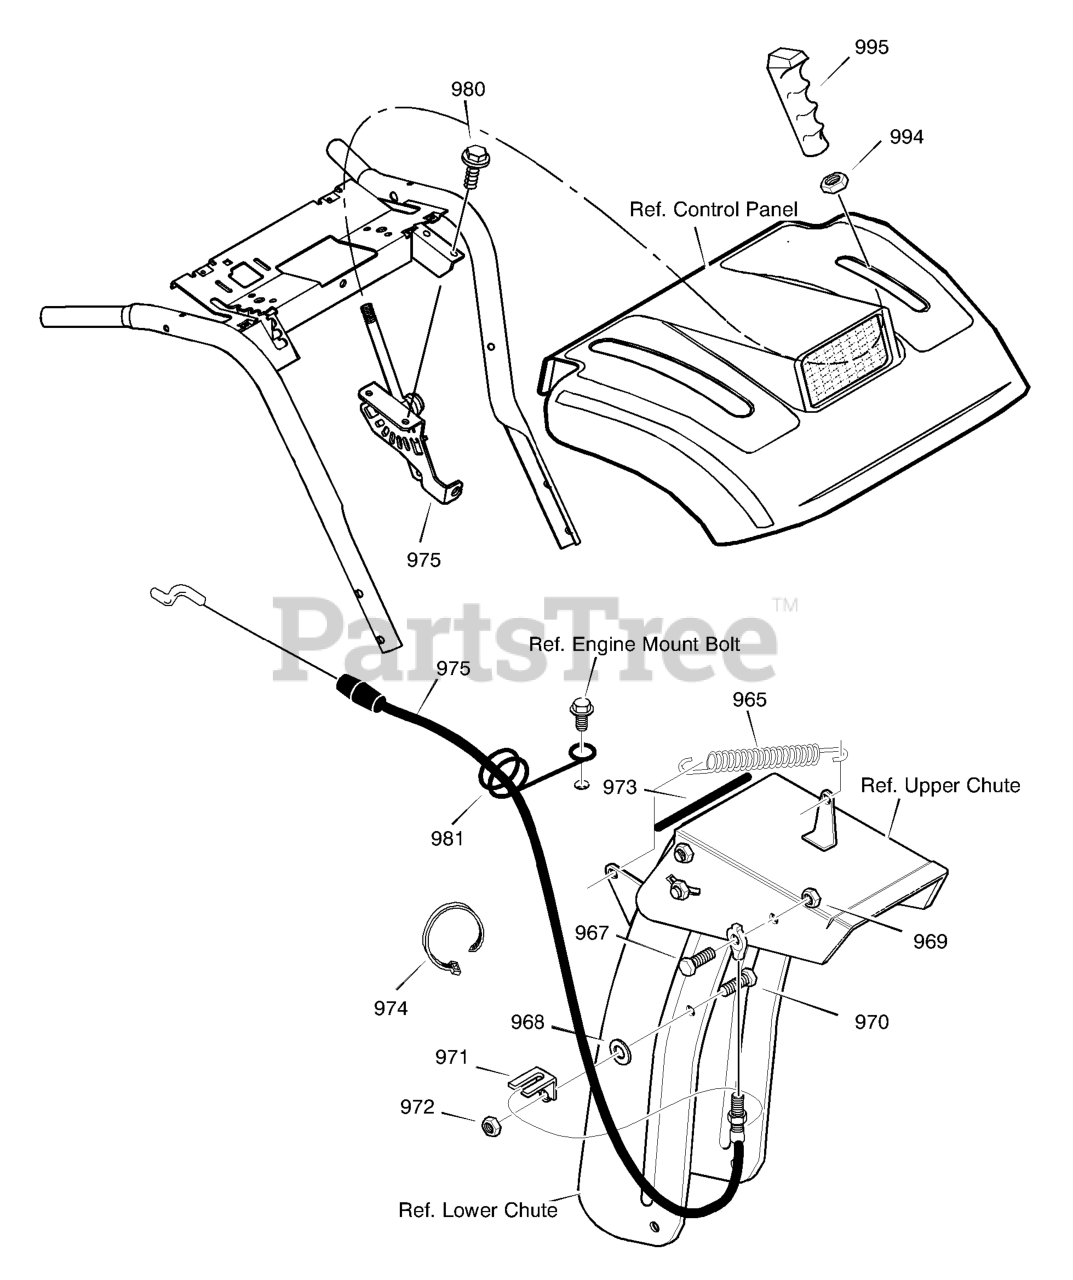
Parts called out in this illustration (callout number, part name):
965	TENSION SPRING
967	BOLT, SHOULDER
968	FLATWASHER
970	SCREW, 5/16-18 x 0.75
971	BRACKET, CABLE CHUTE
972	NUT, 5/16-18
973	TRIM STRIP, BLACK
974	TIE, CABLE
975	CABLE, CHUTE DEFLECTOR
980	SCREW
981	WIRE FORM, CHUTE CABLE
994	NUT, 3/8-16
995	KNOB, SHIFT
